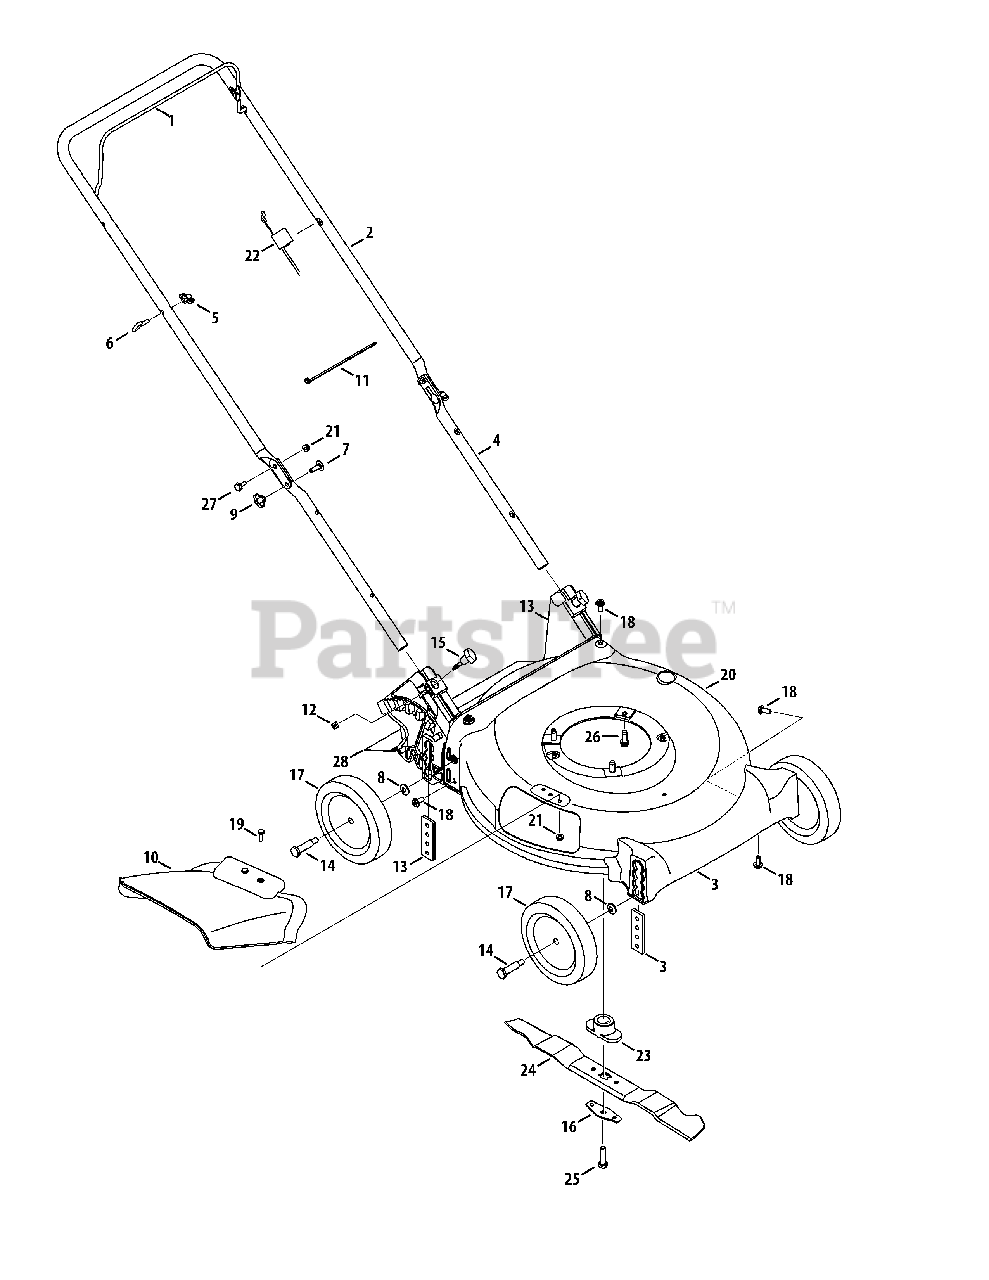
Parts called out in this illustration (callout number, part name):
1	Blade Control
2	Upper Handle
3	Front Cover Assembly
4	Lower Handle
5	Wing Nut
6	Rope Guide
7	Carriage Screw ,5/16-18
8	Washer, .401 x .870 x .060
9	Wing Knob
10	Side Chute
11	Cable Tie
12	Nut, Sq., 1/4-20
13	Rear Baffle
14	Shoulder Screw
15	Wing Nut
16	Blade Bell Support
17	Wheel, 7" Star-Dia., Oys. Gray
18	Screw, 5/16-14 x .750
19	Screw, 1/4-20 x .750
20	Deck , 21"
21	Nut, Flange Lock, 1/4-20
22	Control Cable
23	Blade Adapter
24	Mulching Blade
25	Screw , 3/8-24 x 1.50
26	TT Sems Screw, 3/8-16 x 1.0
27	Sldr. Screw, .375 x .126 x 1/4-20
28	Trail shield
